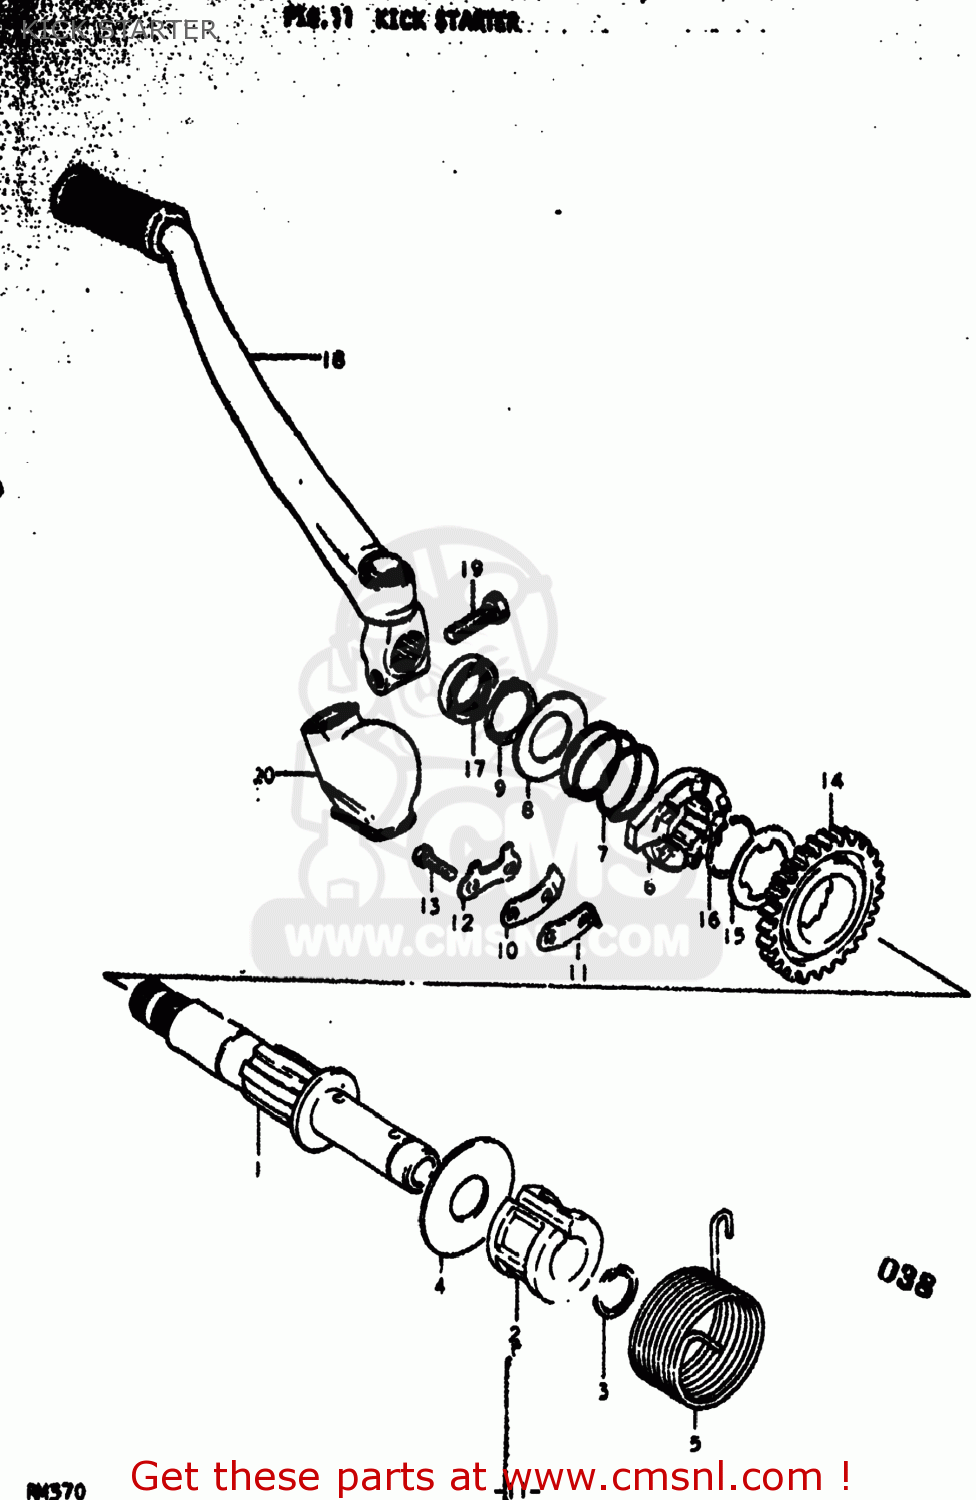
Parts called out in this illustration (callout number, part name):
1	SHAFT,KICK STARTER
2	GUIDE,KICK SHAFT SPRING
3	CIRCLIP
4	WASHER
5	SPRING
6	STARTER,KICK
7	SPRING
8	WASHER
9	CIRCLIP
10	GUIDE,KICK STARTER
11	STOPPER,KICK STARTER
12	WASHER
13	BOLT
14	GEAR,KICK STARTER DRIVE
15	WASHER,LOCK
16	RING,SNAP
17	OIL SEAL
18	LEVER ASSEMBLY,KICK STARTER
19	BOLT
20	COVER,KICK LEVER JOINT
